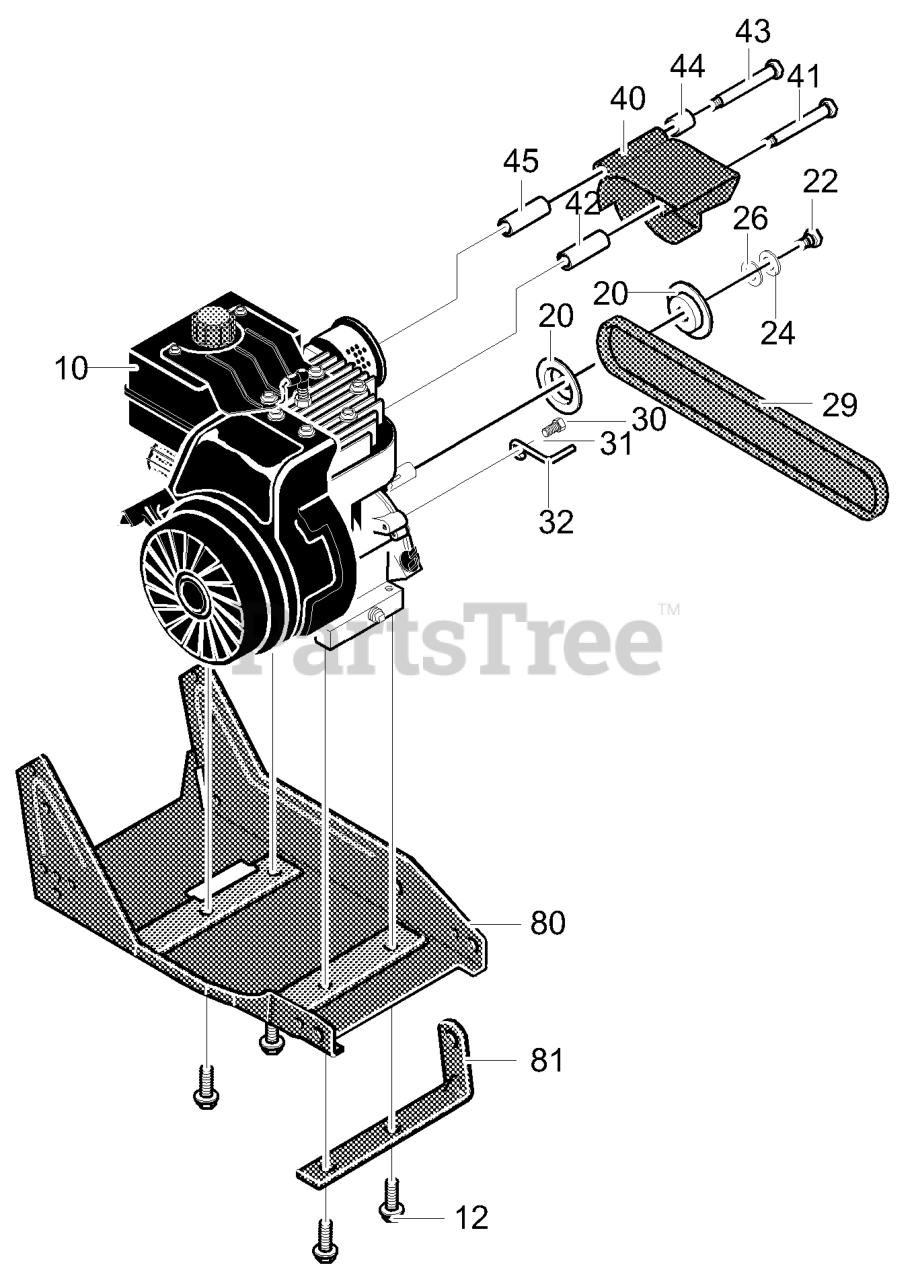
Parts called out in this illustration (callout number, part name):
12	Screw, 3/8-16 x 1.00
20	Pulley, Half
22	Screw, 5/16-24 x 1.00
24	Washer, Hvsptlk
26	Flatwasher
29	Belt, V4L 32.60LG
30	Screw 5/16-24x1.00
31	Flat washer
32	Guide, Belt
40	Cover, Engine Pulley
41	Screw, 5/16-24 x 3.00
42	Spacer, Sleeve
43	Screw, 5/16-24 x 3.75
45	Spacer, Sleeve
80	Frame, Assy. Edger
